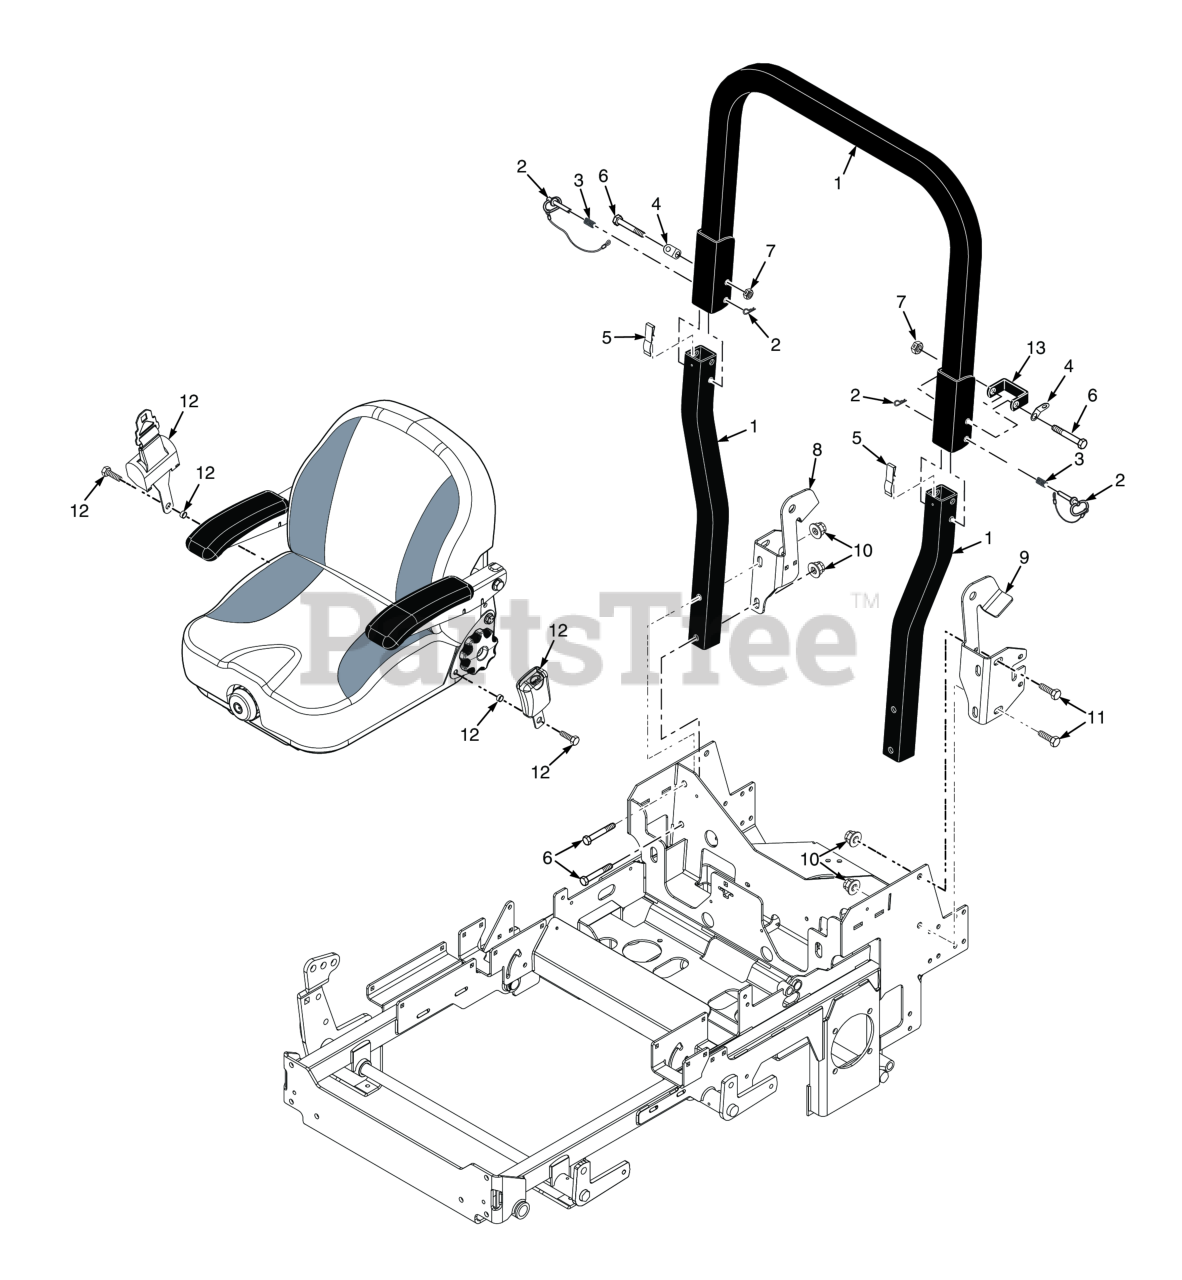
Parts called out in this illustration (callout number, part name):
1	ROPS Assembly, Foldable
2	Pin Assembly, ROPS Hinge
3	Spring, ROPS
4	Clip, ROPS
5	Spring, ROPS Anti-Rattle
6	Bolt, Hex Head, 1/2-13 x 3-1/4"
7	Locknut, Hex 1/2-13 Center Lock
8	ROPS Mount, RH, 22 & 23FX/ 23CV / 24FT / 26FT-EFI / 25CV-EFI
9	ROPS Mount, LH, 22 & 23FX / 23CV / 24FT / 26FT-EFI / 25CV-EFI
10	Nut, Elastic Stop 1/2-13, (STT-52 & STTII-52)
11	Bolt, Hex Head 1/2-13 x 1-1/4"
12	Seat Belt Kit (Suspension Seat)
13	Stop, ROPS
